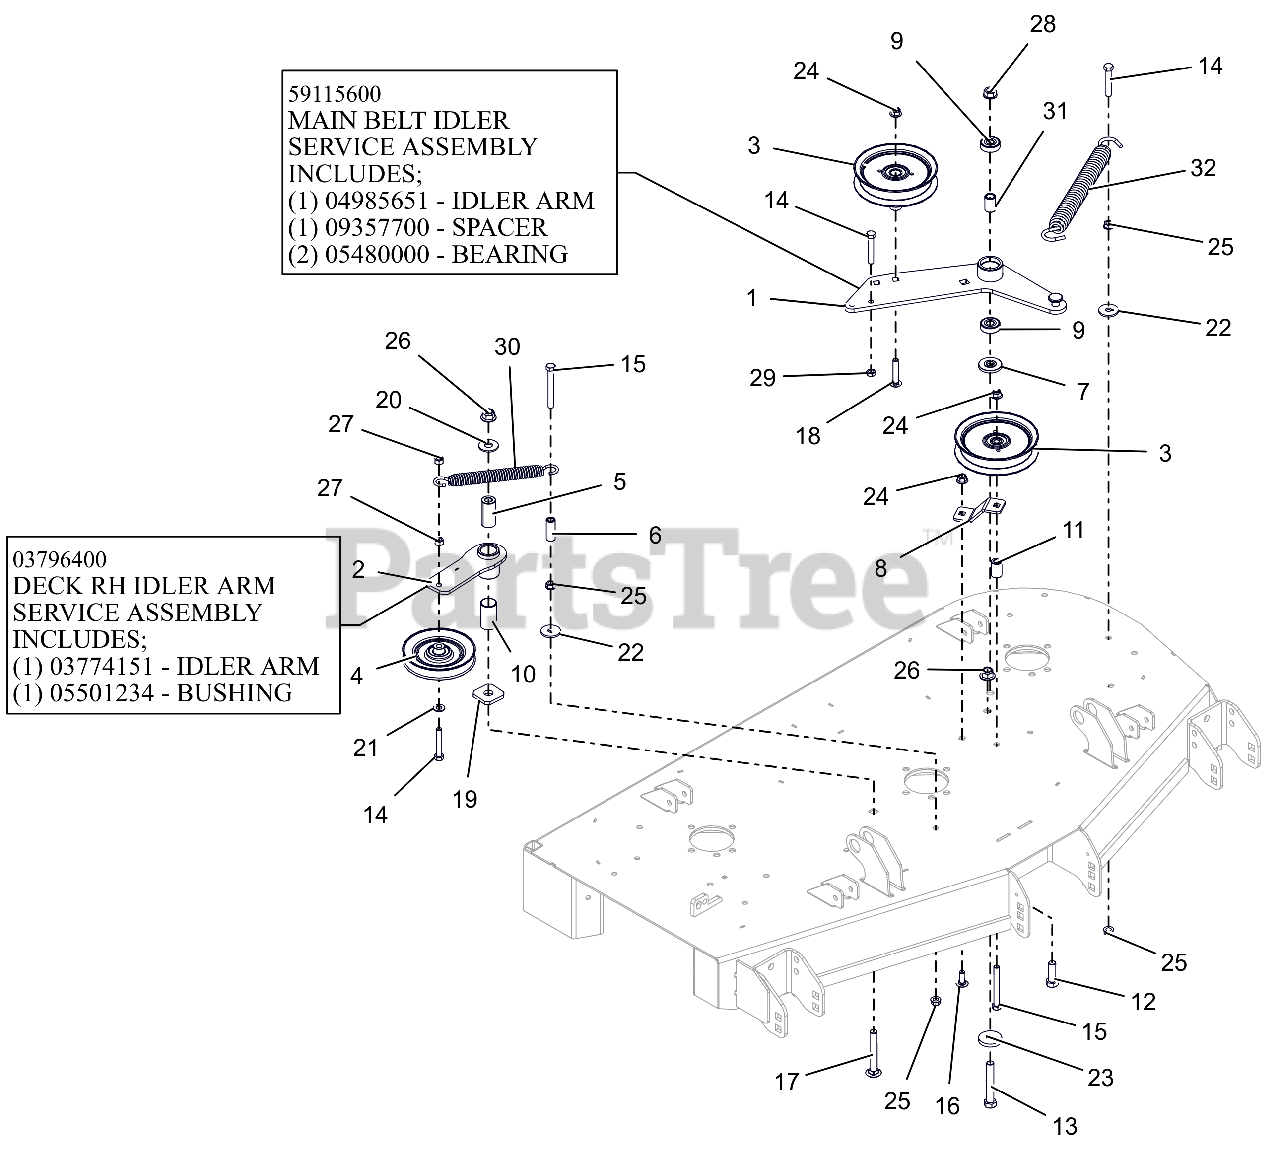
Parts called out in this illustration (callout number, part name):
1	DECK PTO IDLER ARM WLDMT - BLK
1	ASSEMBLY, MAIN BELT IDLER
2	WMT, IDLER ARM - BLACK
2	ASM, IDLER ARM (DECK)
3	IDLER, FLAT 5.00"
4	IDLER, V-5.00"
5	BSHG, SPCR .502X.997X2.03 PM
6	SPACER, .375IDX.625ODX1.66 PM
7	SPACER, IDLER ARM
8	PTO FIXED IDLER MTG BRKT -RED
9	BRG-BALL .500X1.38X.437
10	BSHG, 1.00X1.125X1.937
11	BUSHING, SLV .380X.750X1.190
12	BLT,HEX .50-13X1.50 G5 ZCC
13	BLT,HEX .50-13X3.25 G5 ZCC
14	BLT,HEX .38-16X2.25 G5 ZCC
15	BLT, HEX .38-16X3.25 G5 ZCC
16	BLT,RHSSN .38-16X1.00 G5 ZCC
17	BLT, RHSN .50-13X3.50 G5 ZCC
18	BLT,RHSSN.375-16X2.00 G5 ZCC
19	WSHR-FLT .640X1.75X.250
20	WSHR,FLT .563X1.375X.109 ZCC
21	WSHR,FLT .406X.812X.065 ZCC
22	WSHR,FLT .406X1.375X.135 ZCC
23	WSHR-FL-STL 0.557X1.625X0.25 ZCC
24	NUT,NYL-FLG .38-16 GF ZCC
25	NUT, SPNLK-FLG .38-16 G5 ZCC
26	NUT,NYL-FLG .50-13 GF ZCC
27	NUT-LK-CTR .38-16 ZC120
28	NUT-LK-CTR-FLG .500-13 GG ZCC
29	NUT-JAM .375-16 G2 ZCC
30	SPRING, EXTENSION
31	SPACER .510 X .75 X 1.1485
32	SPRING, EXTENSION
